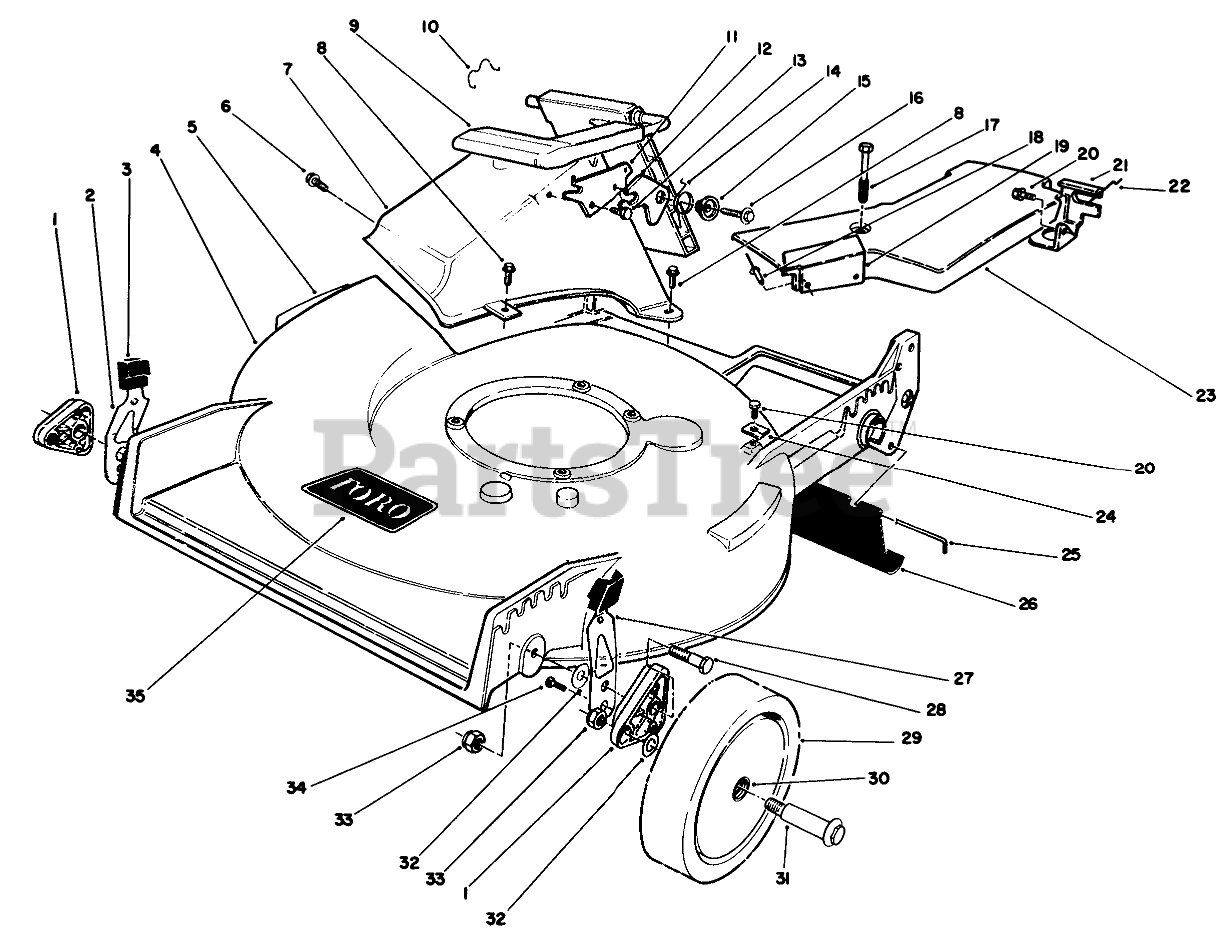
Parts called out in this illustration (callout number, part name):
1	ARM-PIVOT, FRONT
2	RH SPRING ARM ASSEMBLY
3	KNOB-ARM
4	Housing (Incl. Ref. #5 & 8)
5	DECAL-DANGER
6	SCREW AND WASHER ASM
7	Tunnel Discharge
8	SCREW-HWH
9	Discharge Door Assembly
10	DOOR RET SPRING
11	DOOR LATCH PLATE
12	SAFETY LATCH
13	SCREW-PLASTITE
14	TORSION SPRING
15	DOOR SPACER
16	SCREW-HWH
17	SCREW-HHFTF
18	RIVET-HEAD, FLAT
19	HEAT SHIELD
20	SCREW-HWHTF
21	Bracket-Traction Adj.
22	RETAINER-CABLE
23	Belt Cover Assembly (Incl. Ref. #18-19)
24	CLAMP-CABLE
25	Rod Shield
26	SHIELD - TRAILING
27	LH SPRING ARM ASSEMBLY
28	BOLT-SHOULDER
29	Wheel & Tire Assembly (Incl. Ref. #30)
30	BUSHING
31	WHEEL BOLT
32	WASHER
33	Nut
34	SCREW-HWH
35	DECAL
